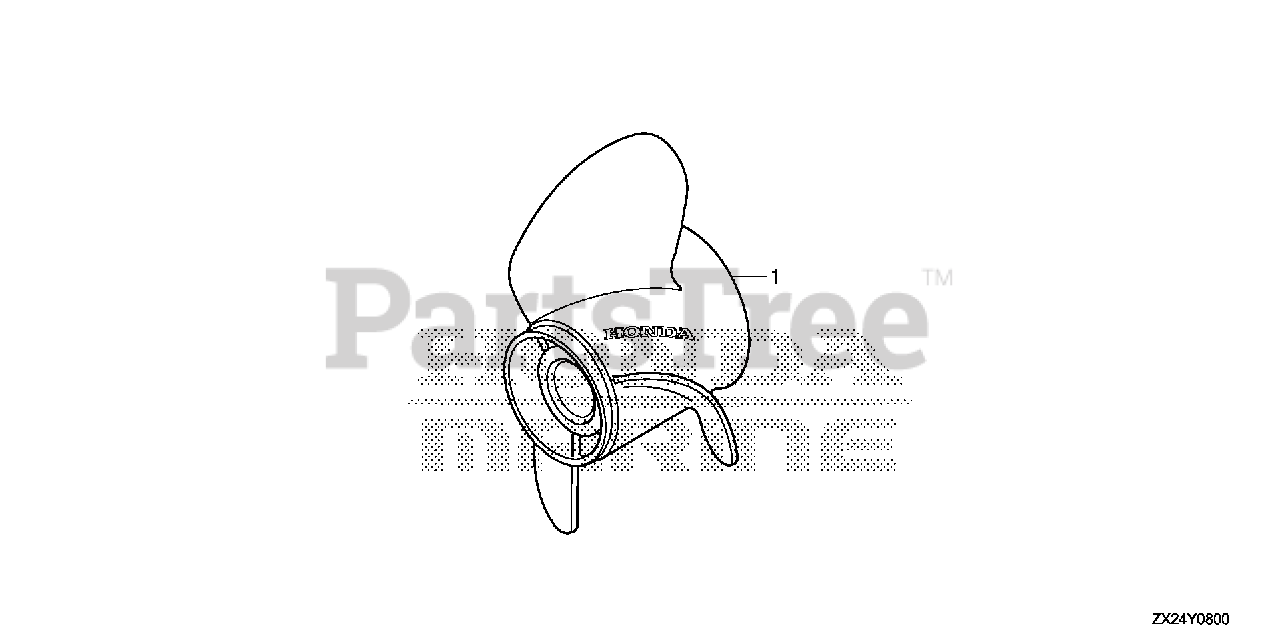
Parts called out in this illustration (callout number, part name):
1	PROPELLER, THREE-BLADE (15-3/4X15) (C/R)
1	PROPELLER, THREE-BLADE (15-1/2X17) (C/R)
1	PROPELLER, THREE-BLADE (15-1/4X19) (C/R)
1	PROPELLER, THREE-BLADE (15X21) (C/R)
1	PROPELLER, THREE-BLADE (14-3/4X23) (C/R)
1	PROPELLER, THREE-BLADE (14-1/2X25) (C/R)
1	PROPELLER, THREE-BLADE (14-1/2X27) (C/R)
